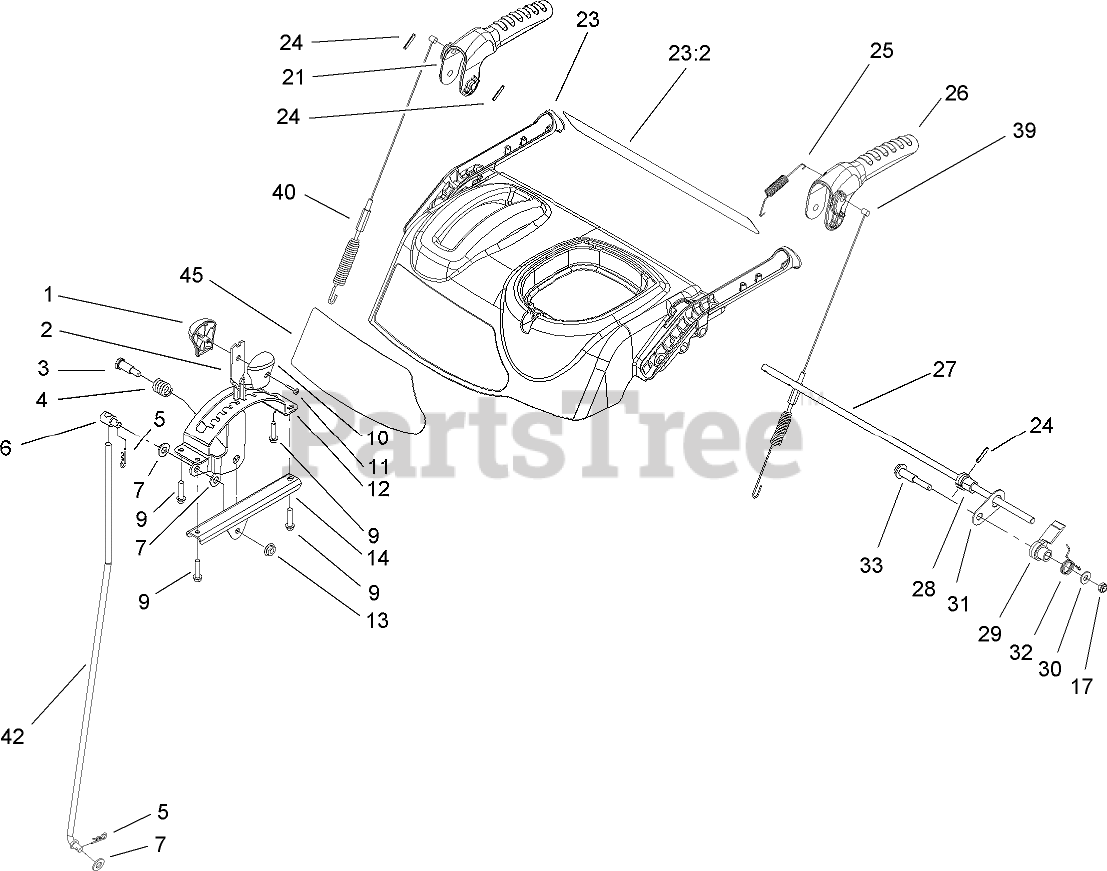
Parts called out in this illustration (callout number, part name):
1	KNOB-SHIFT, RH
2	SELECTOR-SPEED
3	SCREW-SHOULDER
4	SPRING-COMPRESSION
5	PIN-COTTER
6	TRUNNION-ROD
7	WASHER-FLAT
9	SCREW-PLASTITE
10	KNOB-SHIFT, LH
11	SCREW-PPH
12	GUIDE-SELECTOR, SPEED
13	NUT-HF
14	MOUNT-SELECTOR, SPEED
17	NUT-LOCK, NI
21	LEVER-AUGER
23	CONTROL PANEL ASM
23:2	DECAL-PANEL, CONTROL
24	PIN-SPRING
25	SPRING-TENSION
26	LEVER-TRACTION
27	ROD-LOCKOUT
28	CAM-LOCKOUT
29	LATCH-LOCKOUT
30	WASHER-FLAT
31	LINK-LOCKOUT
32	SPRING-TORSION
33	SCREW-SHOULDER
39	CABLE-TRACTION
40	CABLE-AUGER
42	ROD-SHIFT
45	DECAL-PANEL, CONTROL
